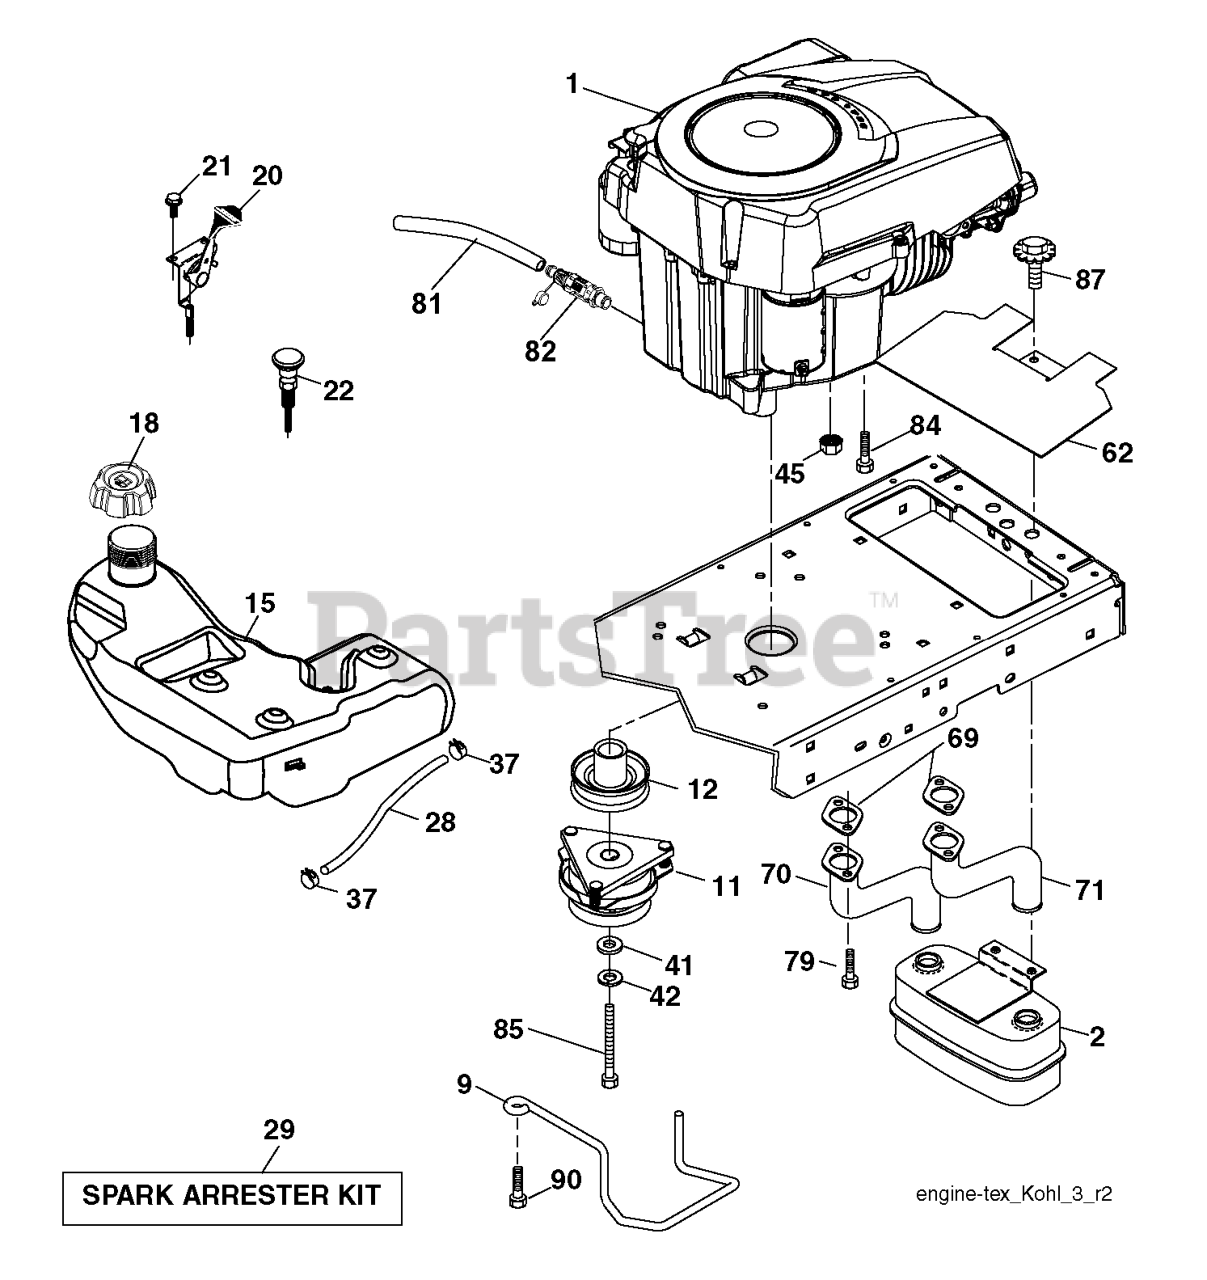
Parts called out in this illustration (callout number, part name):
2	MUFFLER.TWIN.CYL.LOW.TONE
9	KEEPER.BELT.ENGINE.4.2
11	CLUTCH MZ ZTR GT.48/54"1.125"
12	PULLEY ENGINE
15	TANK.FUEL.4GAL
18	CAP.FUEL.TANK.3"GREY
20	THROTTLE CONTROL
21	SCREW.#10 X 0.750.BOS
22	CONTROL.CHOKE.ERGO.PUSH-IN.BLA
28	REPL BY 532 00 85-43
29	KIT.SPARK ARRESTOR 794945 B&S
37	HOSE CLAMP
42	LOCKWASHER
45	NUT
62	RP SHIELD HEAT MUFFLER
70	RP.PIPE-EXHAUST LH
71	RP.PIPE-EXHAUST RH
79	SCREW.SOCKET HD.5/16-1
81	TUBE, DRAIN OIL ASM.
82	VALUE.OIL.DRAIN
84	SCREW 3/8-16X1
85	BOLT HEX 7/16-20 X 3.75 GR. 5
87	BOLT.5/16-18UNCX1.W/SEMS.BLK
90	SCREW 3/8-16X1
